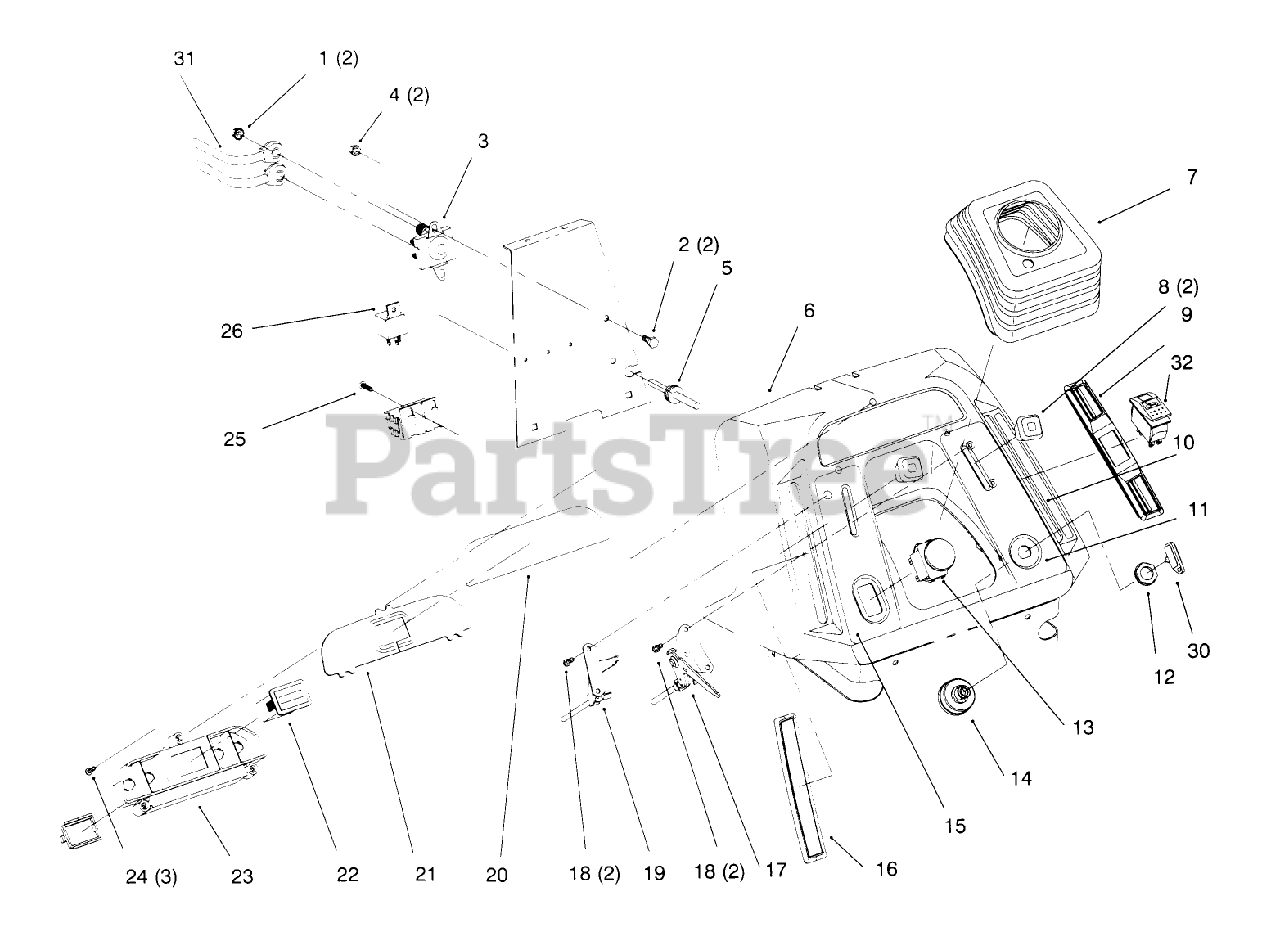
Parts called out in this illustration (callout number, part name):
1	NUT-KEPS
2	SCREW-HH
4	NUT-LOCK, NI
5	GROMMET-RUBBER
7	BOOT-STEERING
9	COVER-SLOT, RH
10	DECAL - SHIFT
11	DECAL-THROTTLE, IGNITION
14	SWITCH-IGNITION
15	DECAL-PTO / CHOKE
15	DECAL - DASH PTO/CHOKE
16	COVER-SLOT, LH
17	CONTROL-THROTTLE
17	CONTROL-THROTTLE (TWIN)
19	CONTROL-CHOKE
19	CONTROL-CHOKE (TWIN)
21	LENS-DASH
23	HOUSING-LIGHT, INDICATOR
24	SCREW-PPH
25	SCREW-PPHTF
26	RELAY
30	KEY-IGNITION
31	WIRE-21 INCH
32	SWITCH-CRUISE
